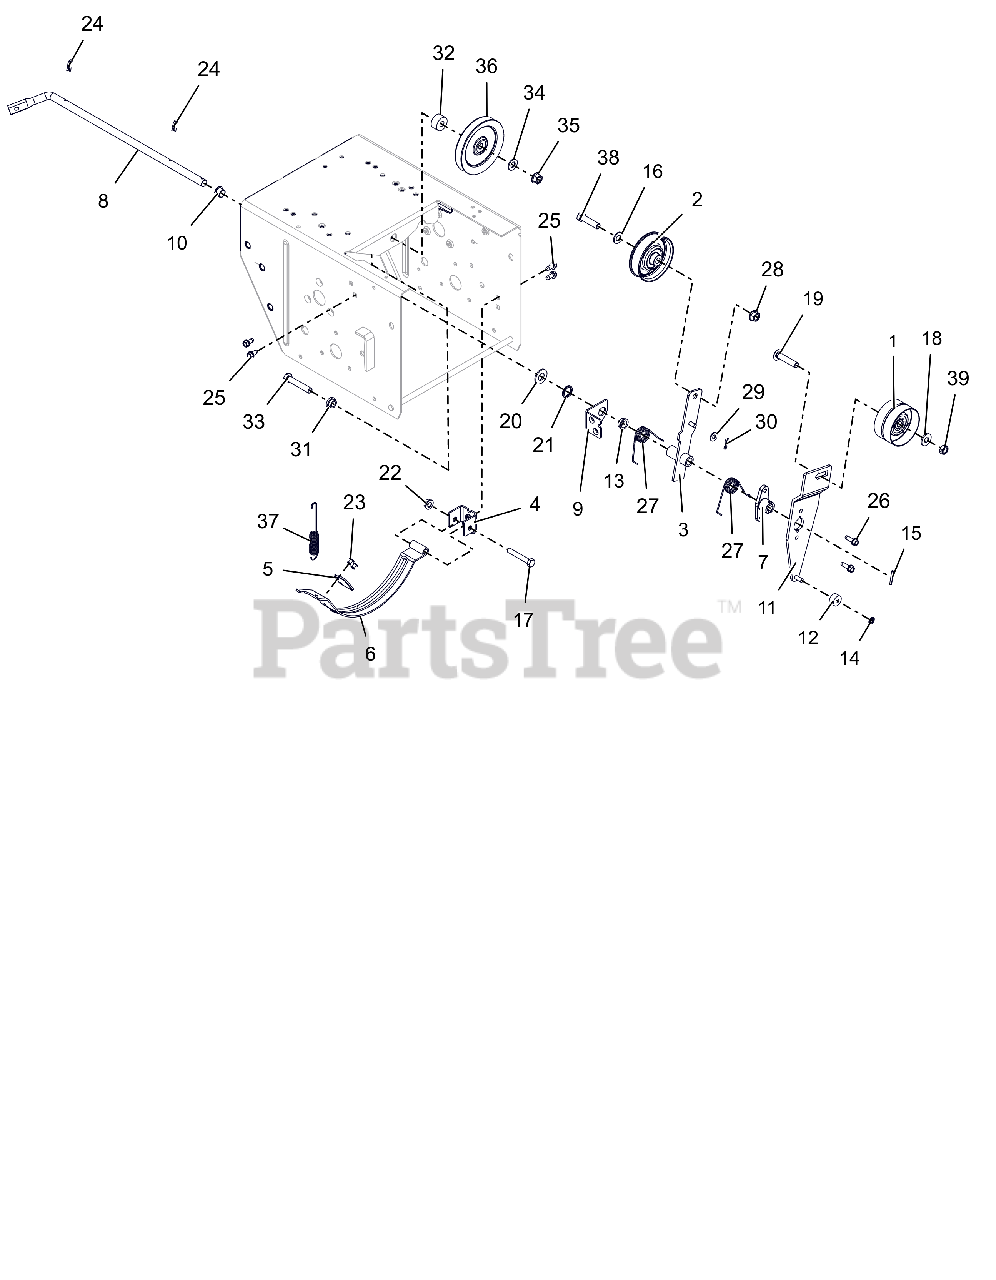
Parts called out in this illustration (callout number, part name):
1	IDLER, FLAT-2.75 OD X .375 ID
2	IDLER, FLAT - 3.05" X .75"
3	ARM, TRACTION CLUTCH
4	PIVOT, BRAKE
5	PAD, BRAKE
6	ARM, BRAKE-ATTACHMENT
7	HUB, BRAKE ARM
8	ARM, ATTACHMENT
9	BRACKET, SUPPORT
10	BUSHING, POLYLINER-.50 SPLIT
11	ARM, IDLER-ATTACHMENT
12	BSHG,SLV .265 X .625 X .375
13	BSHG,FLANGE .500X.625X.270X.75
14	RG-RTNG-EXT .250X.010
15	PIN-ROLL .125X1.00
16	@WSHR-FL-STL.406X.812X.065 YWZ
17	@BLT-HEX .31-18X2.00 GR5 YWZC
18	@WSHR-FL-STL.38X.875X.083 YWZC
19	@BLT-RHDSSQNK .38-16X1.75 G5YZ
20	@WSHR-FL-STL.531X1.06X.095YWZC
21	WAVE SPRING .600X.875X.25FH
22	@NUT-LK-TOP-FLG .31-18 YWZC
23	RVT-POP .187 YZ
24	CLIP, SPRING
25	SCR-TAP .25-20X.50 HWH TR YWZ
26	SCR-TAP-PM .25-20X.75 TR YWZ
27	SG-TORS .067X.88
28	@NUT-LK-TOP-FLG .38-16 YWZC
29	@WSHR-FL-STL.281X.62X.065 YWZC
30	PIN-HAIR INT .06X.18X.77
31	BSHG, FLANGE .391X.56X.313X.75
32	BSHG,POCKET .391X.570X1.0X.450
33	@BLT-HEX .38-16X2.00 GR5 YWZC
34	@WSHR-FL-STL.406X.812X.065 YWZ
35	@NUT-LK-TOP-FLG .38-16 YWZC
36	SHV, .38"ID X 4.00"OD V-IDLER
37	SG-TENS .056X.60X4.40
38	@BLT-HEX .38-16X1.50 GR5 YWZC
39	@NUT-LK-CTR-JAM .375-16 YWZC
